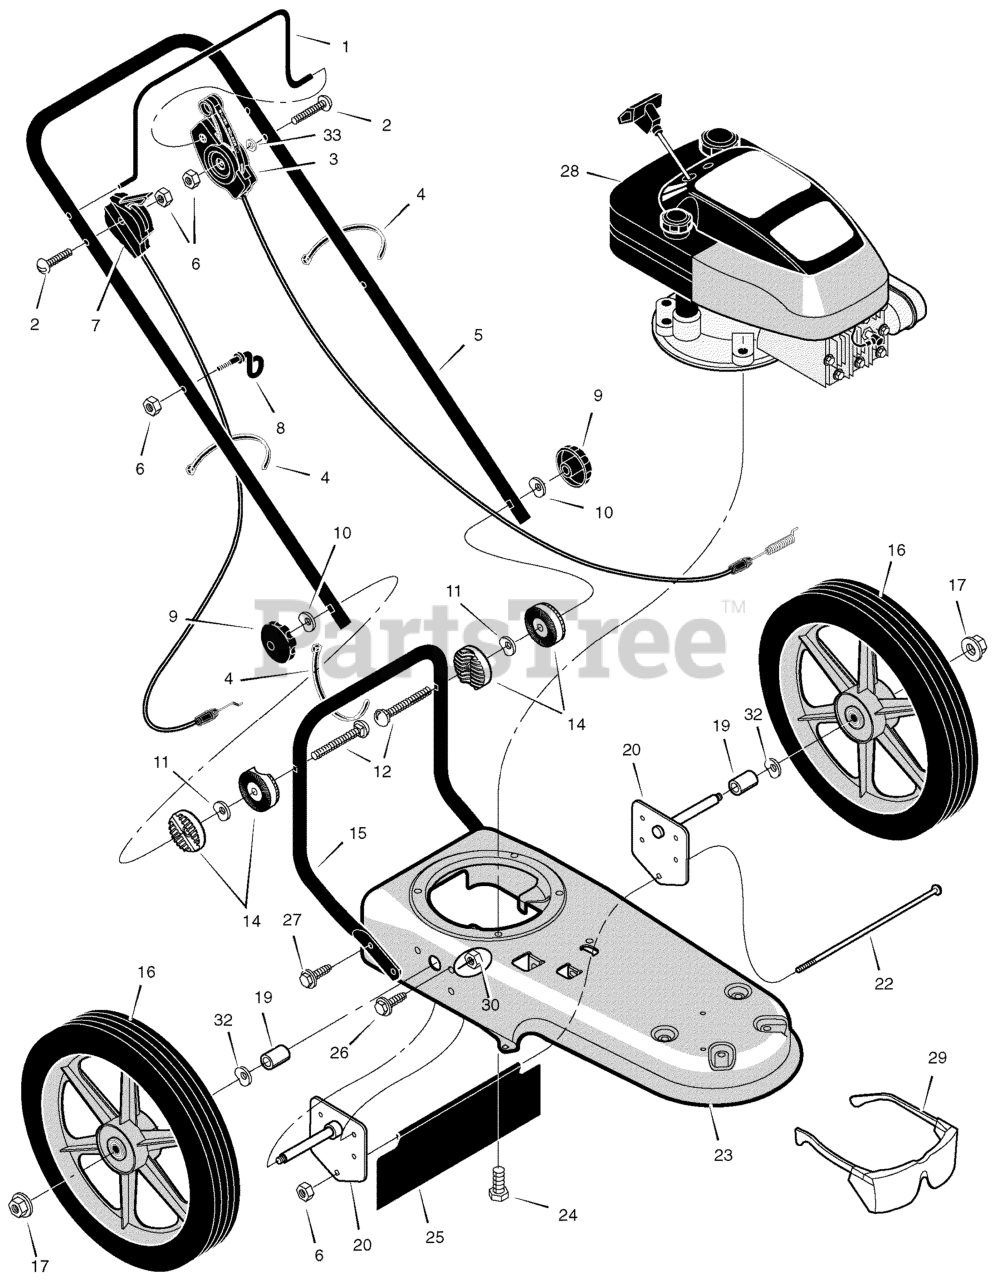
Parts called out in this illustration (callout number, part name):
1	Lever, Stop
3	Cable, Control Latching
4	Tie, Cable
7	Control, Throttle
8	Guide, Rope
9	Knob, Handle
10	Washer
11	Washer, Spring
14	Pivot, Handle
15	Handle, Lower
16	Wheel & Tire
17	Nut, Axle
19	Spacer
20	Assembly, Axle & Bracket
22	Bolt, Carriage
23	Frame, Trimmer
24	Bolt
25	Shield, Trailing
26	Bolt
28	Engine *
29	Protection, Eye
30	Nut
32	Washer, Spring
33	Spacer, PM .26x.5x.2
